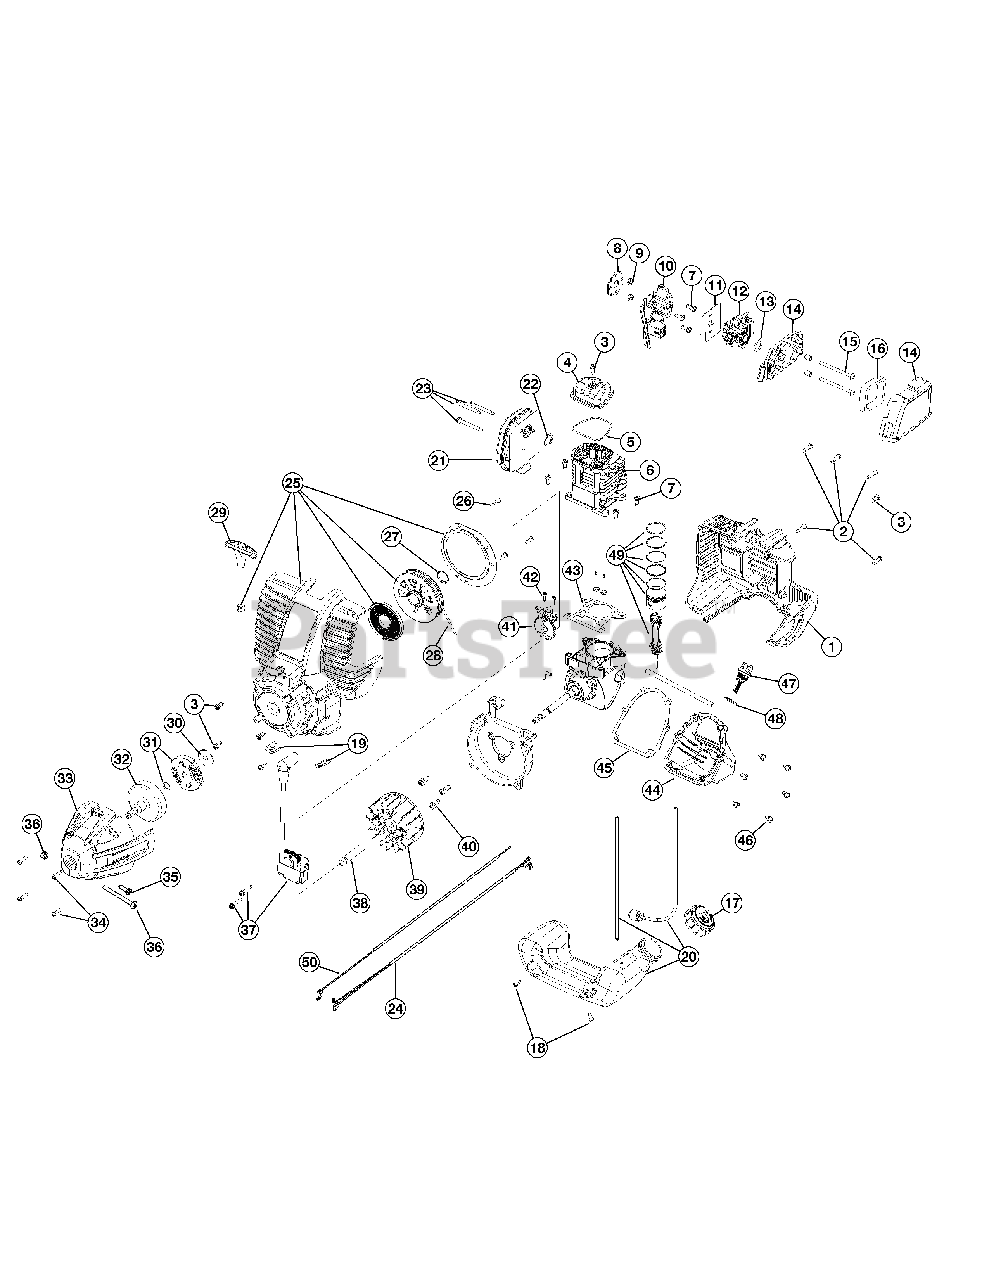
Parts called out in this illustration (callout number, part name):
1	Engine Cover
4	Valve Cover
5	Valve Cover Gasket
6	Cylinder Assembly
7	Cylinder Screw
8	Insulator Gasket
10	Insulator
11	Carburetor Gasket
12	Carburetor w/Primer Carburetor WYL-229
12	Carburetor w/Primer Carburetor WYL-242
14	Air Filter Cover Assembly
15	Air Filter Mounting Screw
16	Air Filter
17	Fuel Cap
19	Clip Nut
20	Fuel Tank Assembly
21	Muffler Assembly
22	Muffler Gasket
23	Muffler Mounting Screw
24	Lead Wire
25	Starter Housing Assembly
26	Plate Screw
27	Push Nut
28	Rope Pull
29	Handle
30	Washer
31	Clutch Assembly
32	Clutch Drum
33	Clutch Cover Assembly
34	Cover Screw
35	Anti-Rotation Screw
36	Clamping Screw Assembly
37	Ignition Module Assembly
38	Spacer
39	Flywheel
40	Shroud Screw
41	Cam Bracket Assembly
42	Cam Bracket Screw
43	Cylinder Gasket
44	Oil Pan
45	Oil Pan Gasket
46	Oil Pan Screw
47	Dipstick Assembly
49	Piston Assembly
50	Throttle Cable
